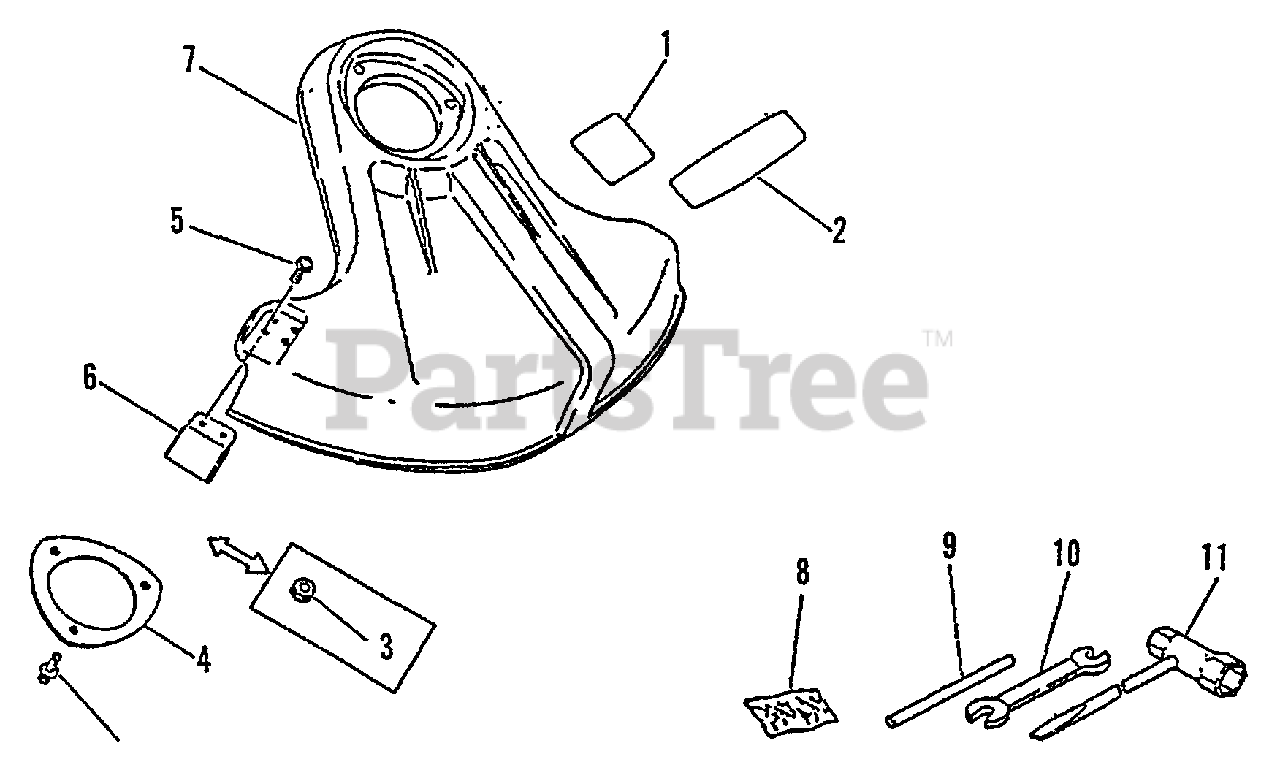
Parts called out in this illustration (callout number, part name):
1	LABEL - CAUTION
2	LABEL - ECHO
4	PLATE, SHIELD
5	SCREW - 5X16
6	KNIFE, TRIMMER LINE
7	SHIELD, DEBRIS
8	PIN, SPLIT - 2X22
9	LOCKING TOOL
10	SPANNER - 8X10mm
11	T-WRENCH - 17X19mm
